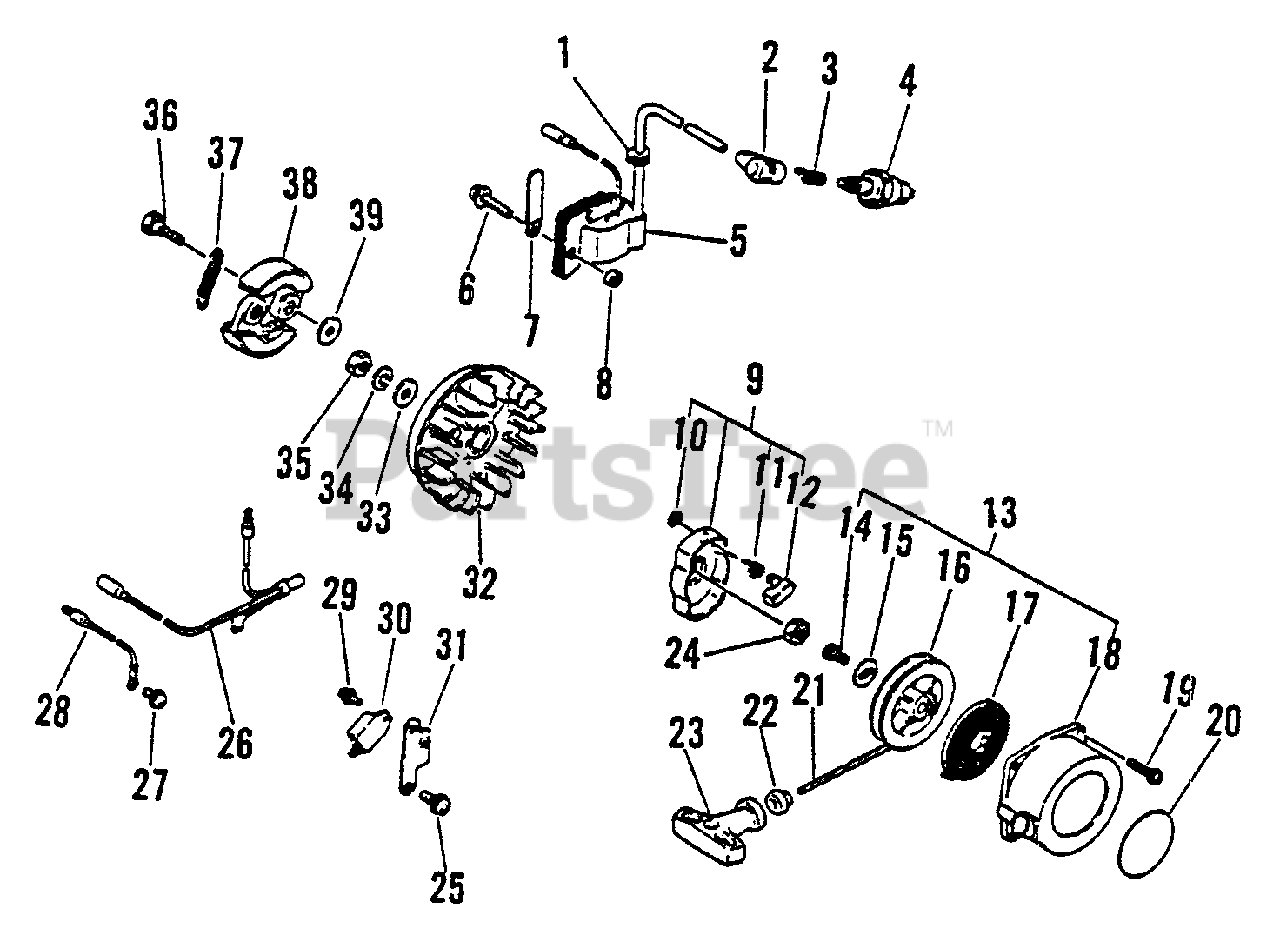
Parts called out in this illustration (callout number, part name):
2	CAP, SPARK PLUG
3	TERMINAL, SPARK PLUG
4	SPARK PLUG - BPM7A
5	COIL, IGNITION
6	SCREW 5×25
8	WASHER 5.2×12×3
9	PAWL ASSY, STARTER
10	E-RING 4
11	SPRING, RETURN
12	PAWL, STARTER
13	STARTER ASSY
16	REEL, ROPE
17	SPRING, RECOIL
18	CASE, STARTER - ORANGE
19	SCREW 4×20
20	LABEL, ECHO
21	ROPE, STARTER 4.0×880
22	GUIDE, ROPE
23	GRIP, STARTER
24	NUT 8×1.25
25	SCREW 5×12
27	SCREW 5×10
28	LEAD - GROUND L= 115
29	SCREW 4×8
30	COIL, IGNITION
31	BRACKET, IGNITION COIL
32	FLYWHEEL
33	WASHER 8.2×17×1.6
34	WASHER, SPRING 8
36	BOLT, CLUTCH
37	SPRING, CLUTCH
38	SHOE, CLUTCH
39	WASHER 6.2×19×1.0
